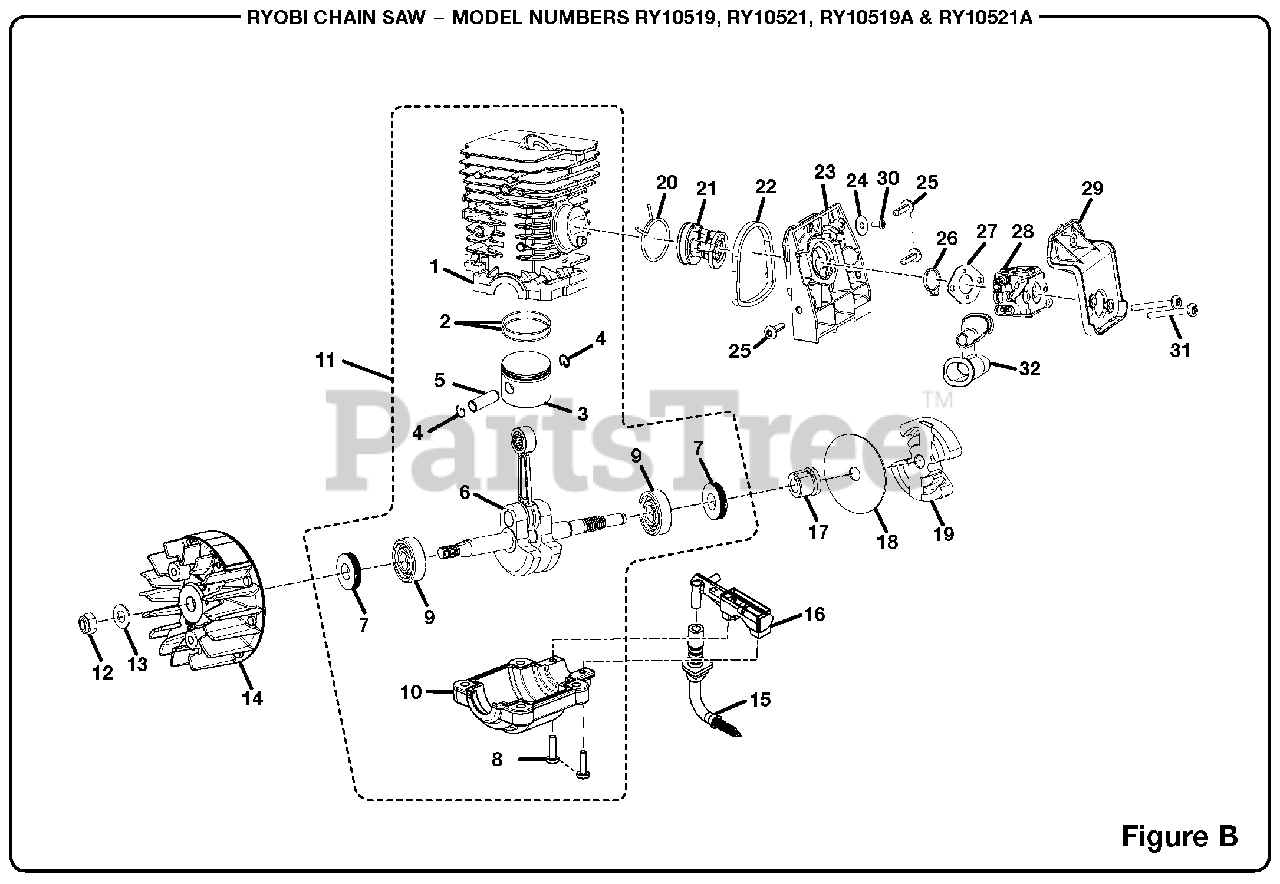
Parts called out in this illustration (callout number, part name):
2	Piston Ring
4	Retaining Ring
5	Piston Pin
6	Crankshaft Assembly
7	Shaft Seal
8	Screw (8-32 x 5/8 in.)
9	Ball Bearing
10	Crankcase
11	Short Block Assembly (Inc. Key Nos. 1-10)
12	Lock Nut (M8)
13	Washer
14	Flywheel Assembly
15	Oil Intake Tube Assembly
16	Oil Pump Assembly
17	Left Hand Worm
18	Thrust Washer
19	Clutch Assembly
20	Wire Clamp
21	Intake Boot
22	Carburetor Adaptor Seal
23	Carburetor Adapter
24	Washer
25	Screw (10-14 x 3/4 in., T.F.)
26	Carburetor Plate
27	Carburetor Gasket
28	Carburetor Assembly
29	Air Filter Base
30	Screw (8-16 x 5/16 in.)
31	Screw (10-32 x 1 3/4 in.)
